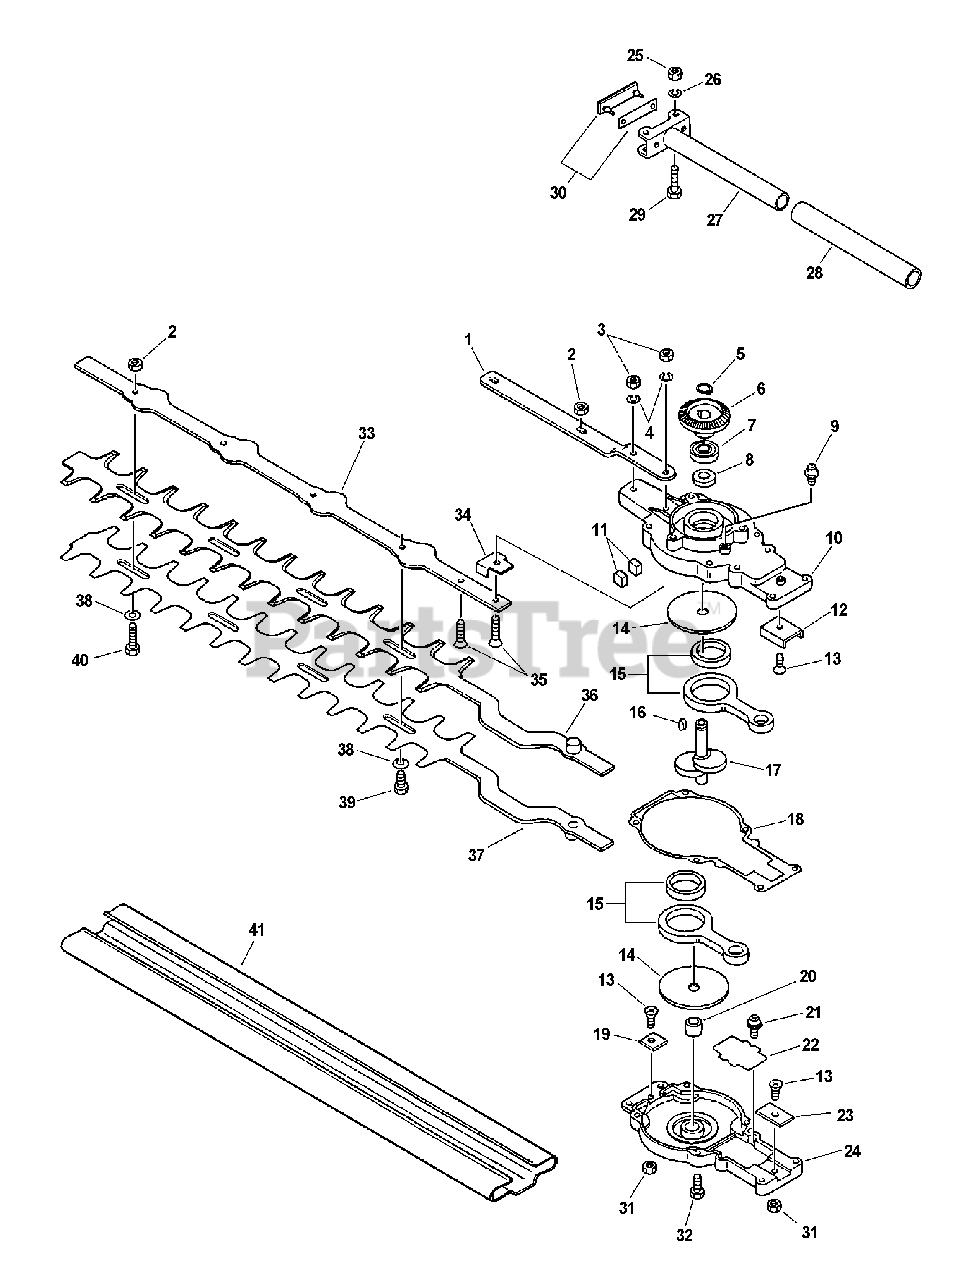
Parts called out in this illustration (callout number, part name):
1	SUPPORT, BLADE
3	NUT M5
4	WASHER, SPRING 5
5	E-RING 10
6	GEAR, SPUR
7	BEARING, BALL 6000
8	SEAL, OIL
9	FITTING, GREASE
10	CASE, GEAR
13	SCREW 4×8
14	PLATE, SIDE
15	CONROD ASSY
18	GASKET, GEAR CASE
19	PLATE, GUIDE
20	BEARING, PLAIN
21	SCREW 3×6
22	PLATE, SIDE
23	PLATE, EYE
24	COVER ASSY
25	NUT M5
26	WASHER, SPRING 5
27	ADJUSTOR ASSY, HANDLE
28	GRIP, HANDLE
29	BOLT - 5×25
30	PLATE, EYE
32	BOLT 5×20
33	SUPPORT, BLADE
34	PLATE, ANGLE
35	SCREW 5×20
36	BLADE - UPPER -- "TB"- TOP BLADE
37	BLADE, TRIMMER - "BB"- BOTTOM BLADE
38	WASHER 6.5×15.5×0.6
39	BOLT, CUTTER
40	BOLT, CUTTER
41	SCABBARD
